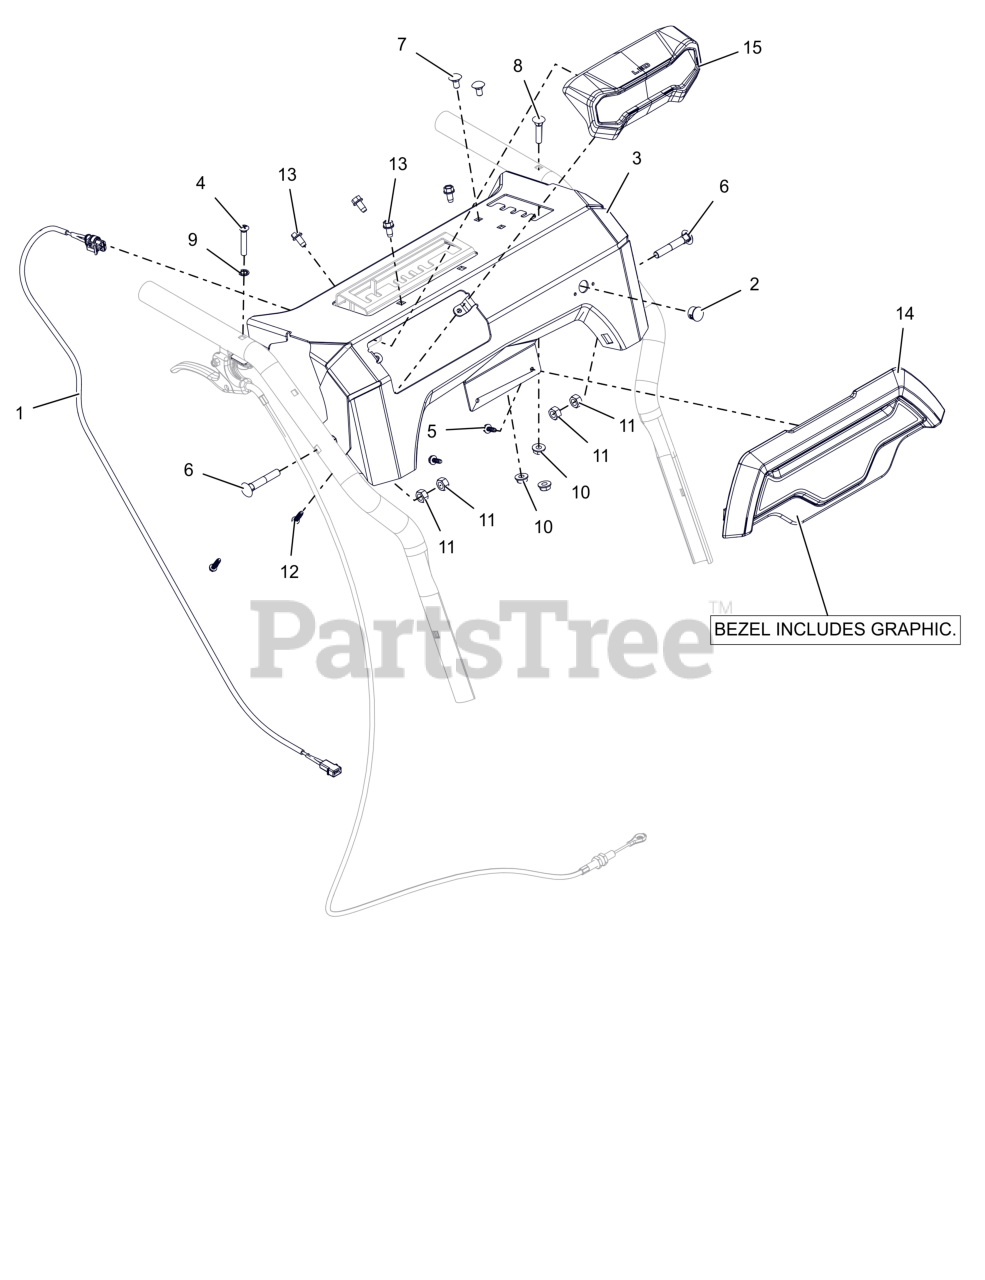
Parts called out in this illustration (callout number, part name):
1	HARNESS- WIRE - LT
2	HOLE PLUG, PLASTIC .56 HOLE
3	PANEL, DASH - COMPACT
4	SCR,OVAL .25-20X1.50 ZCC
5	SCR, PLASTIC #10X.50
6	BLT-RDHDXLSQNK .31-18X2.0 G5YZ
7	BLT, RHSN .25-20X.500 G5 ZCC
8	BLT-RDHDXLSQNK.25-20X1.25 G5ZC
9	WSHR-LK-INT .250 TH TYA
10	NUT-LK-CTR-FLG .25-20 ZC120
11	NUT,LK-CTR .31-18 GA ZCC
12	SCR-HWH 10-16X.75 HI-LO ZCC
13	SCR-TAP .25-20X.50 HWH ZCC
14	BEZEL, SMALL - COMPACT
15	HEADLIGHT ASM- LED
